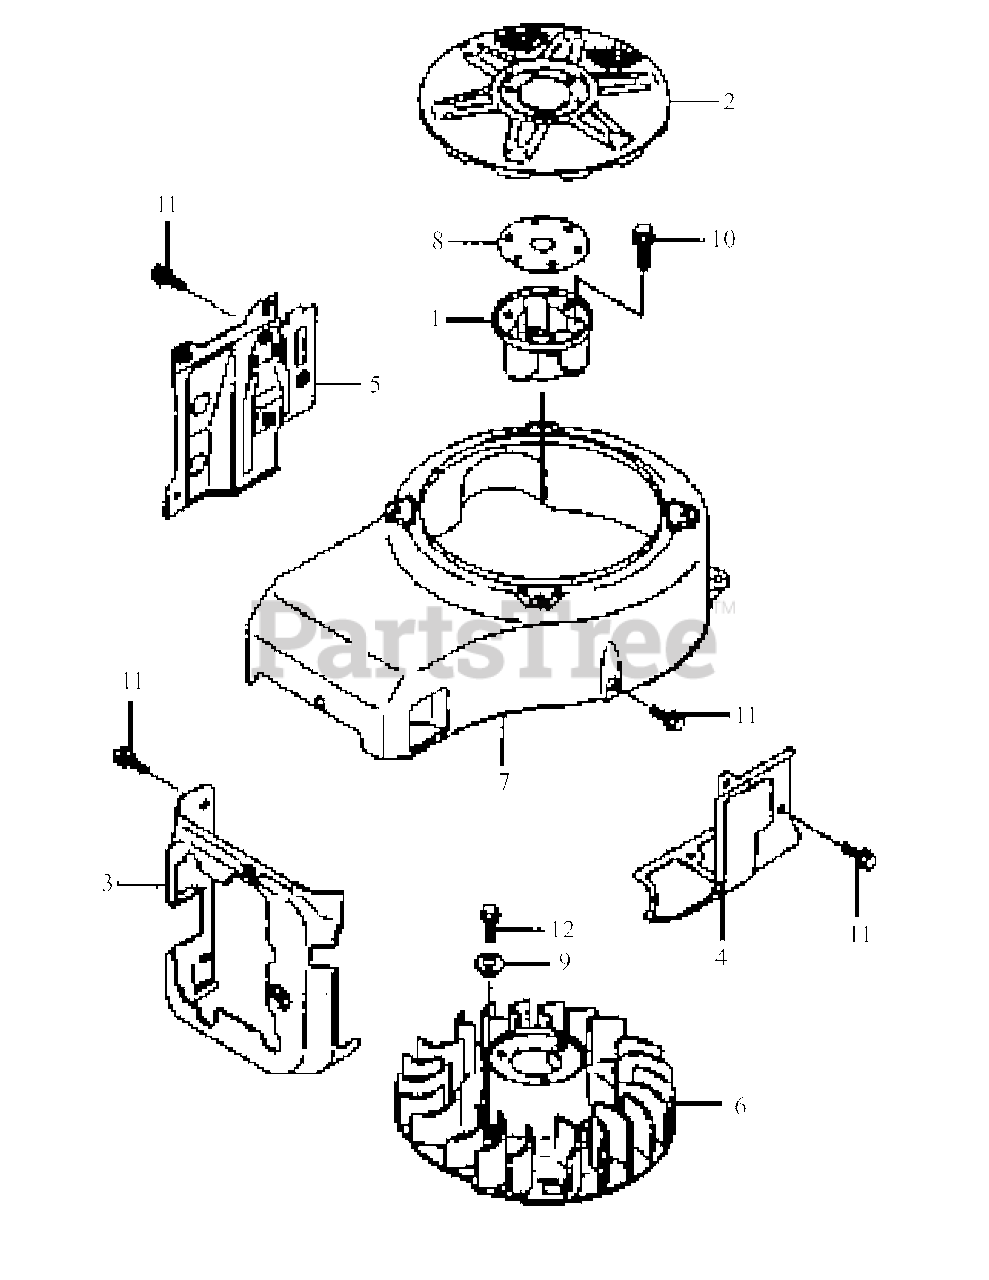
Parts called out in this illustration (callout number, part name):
3	Shroud, Engine
4	Shroud, Engine
5	Shroud, Engine
8	Shim, T=1.20
10	Bolt, Flange
11	Bolt, Flange
12	Bolt, Flange
